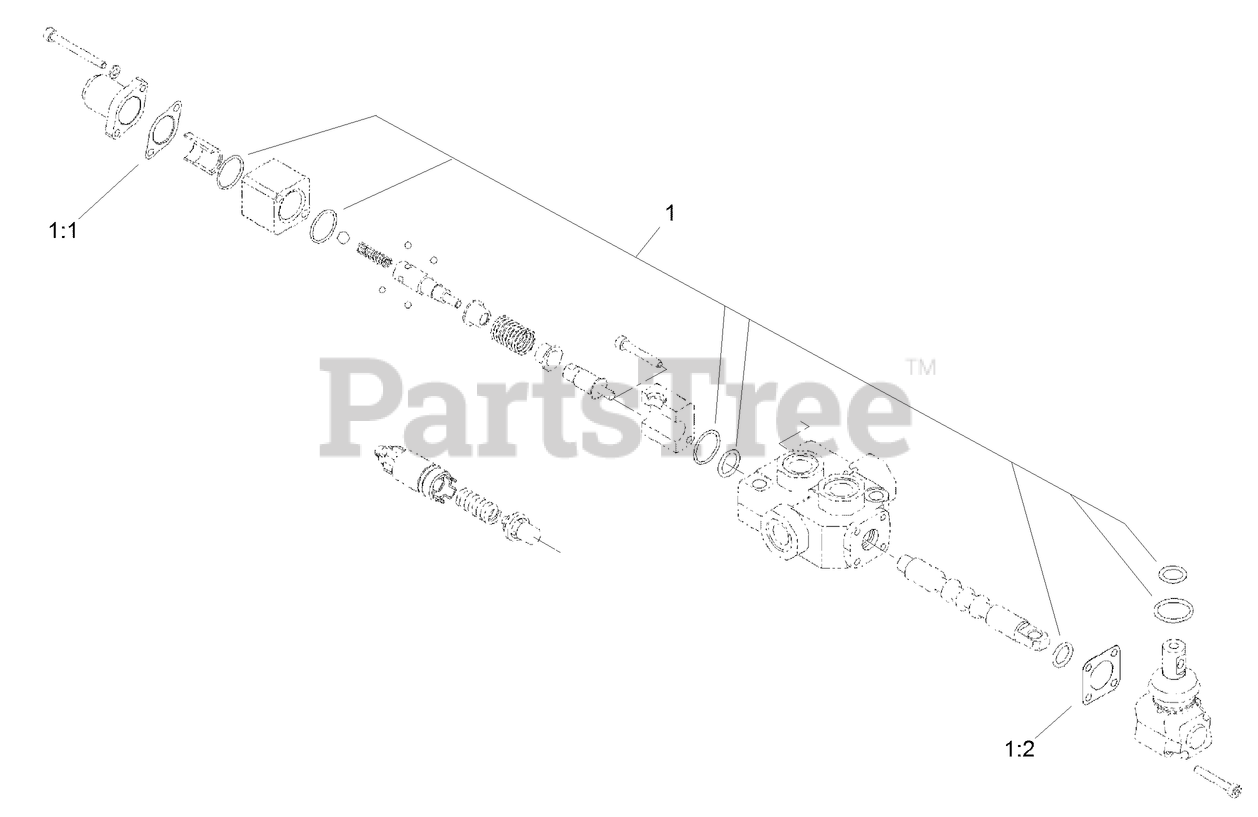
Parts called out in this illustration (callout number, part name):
1	SEAL KIT
1:1	GASKET
1:2	GASKET
